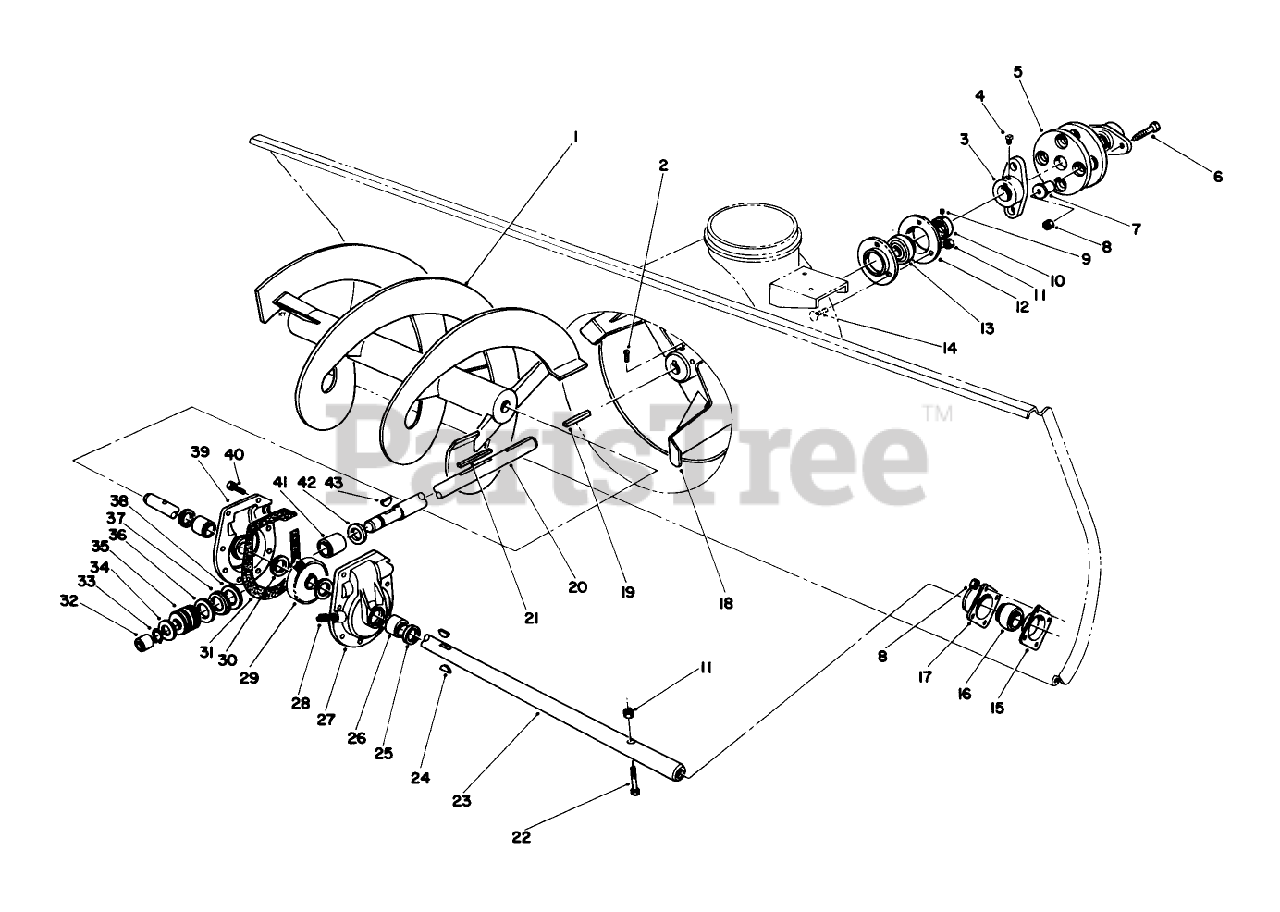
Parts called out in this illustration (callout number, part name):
2	SCREW-SET, SQH
4	SCREW-SET
6	SCREW-HH
7	SPACER-COUPLING, RUBBER
8	NUT-LOCK, NI
9	SCREW-HSH
10	EXT LOCKING COLLAR
11	NUT-LOCK, NI
12	BRG FLANGE
13	BALL BRG W/COLLAR
14	BOLT-CARR
15	BEARING-FLANGE, REAR
16	BEARING
17	BEARING-FLANGE, FRONT
19	KEY-SQUARE
22	SCREW-HH
23	SHAFT-AUGER
24	KEY-WOODRUFF
25	SEAL-OIL
26	BUSHING
28	PLUG-PIPE, SQH
29	GEAR-WORM, 27T
30	WASHER-THRUST
31	GASKET-CASE, GEAR
32	BUSHING
33	RING-SNAP
34	WASHER-THRUST
36	THRUST-WASHER
37	BEARING-THRUST
38	WASHER-THRUST
40	SCREW-TAPTITE
41	BUSHING-SPECIAL
42	RING-QUAD
43	KEY-WOODRUFF
